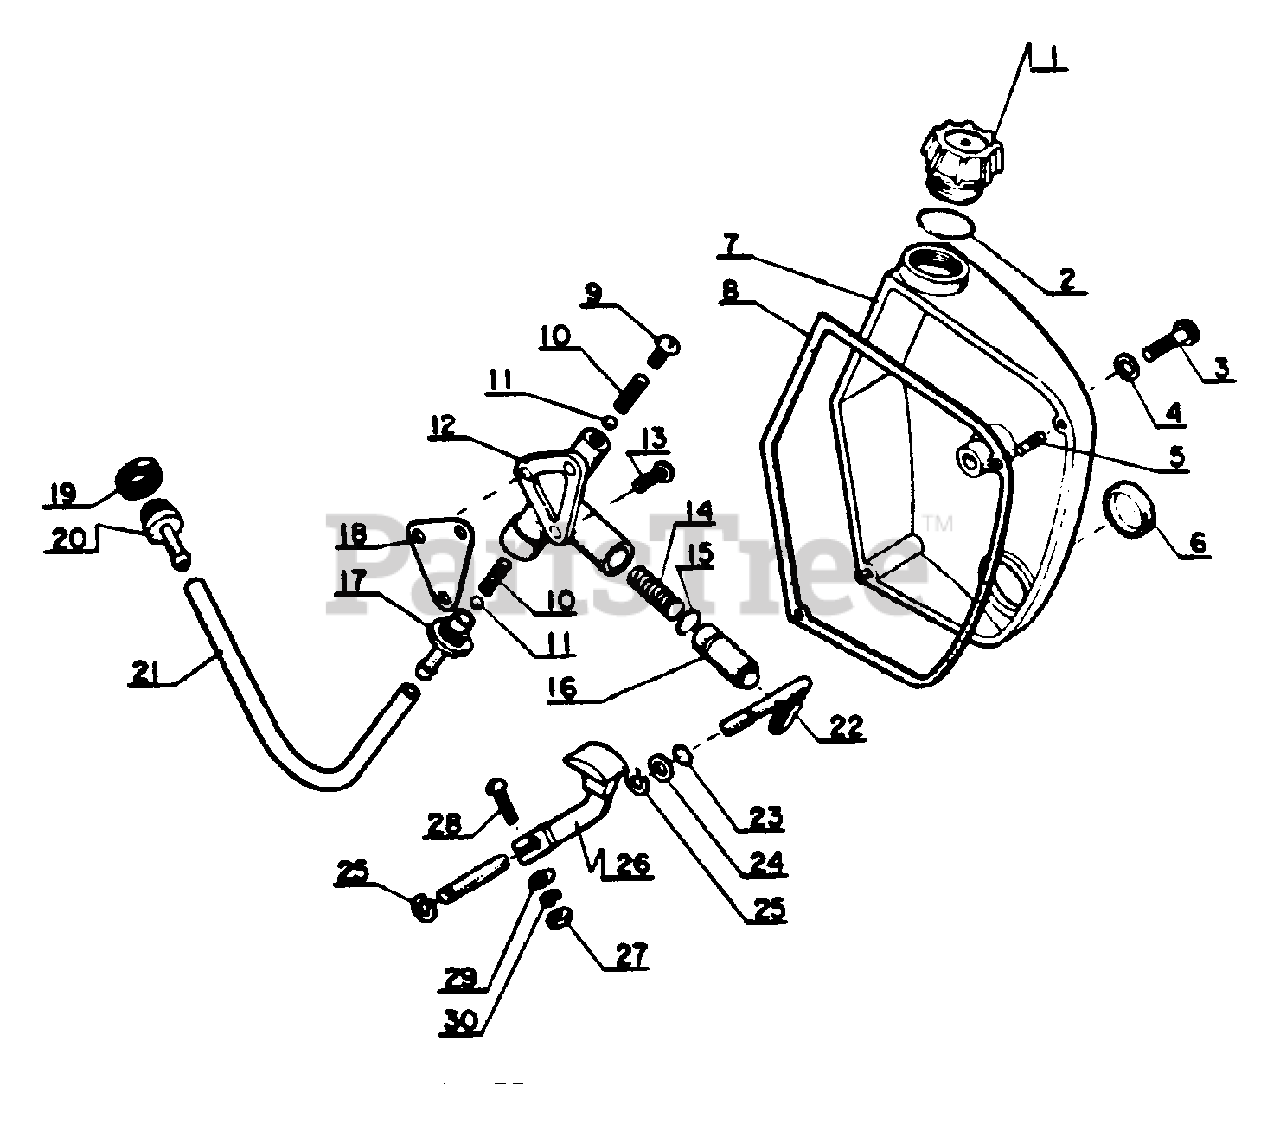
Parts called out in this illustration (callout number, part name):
1	CAP
2	GASKET, CAP
3	BOLT
4	WASHER
5	PIN - LOCATING
6	GAUGE, OIL
7	TANK, OIL
8	GASKET
9	SCREW - 6X5
10	SPRING, VALVE
11	VALVE, BALL
12	BODY, OIL PUMP
13	SCREW
13	SCREW - 5X16
14	SPRING, PUMP
15	O-RING
16	PISTON, OIL PUMP
17	NIPPLE
18	PACKING
19	COVER, OIL FILTER
20	FILTER, OIL
21	PIPE, OIL - INNER
22	Push lever
23	O-RING
24	WASHER
25	RING, RETAINING - 4
26	Push lever
27	NUT
27	NUT - 5
28	SCREW
28	SCREW - 5X14
29	WASHER - 5
30	LOCKWASHER - 5
